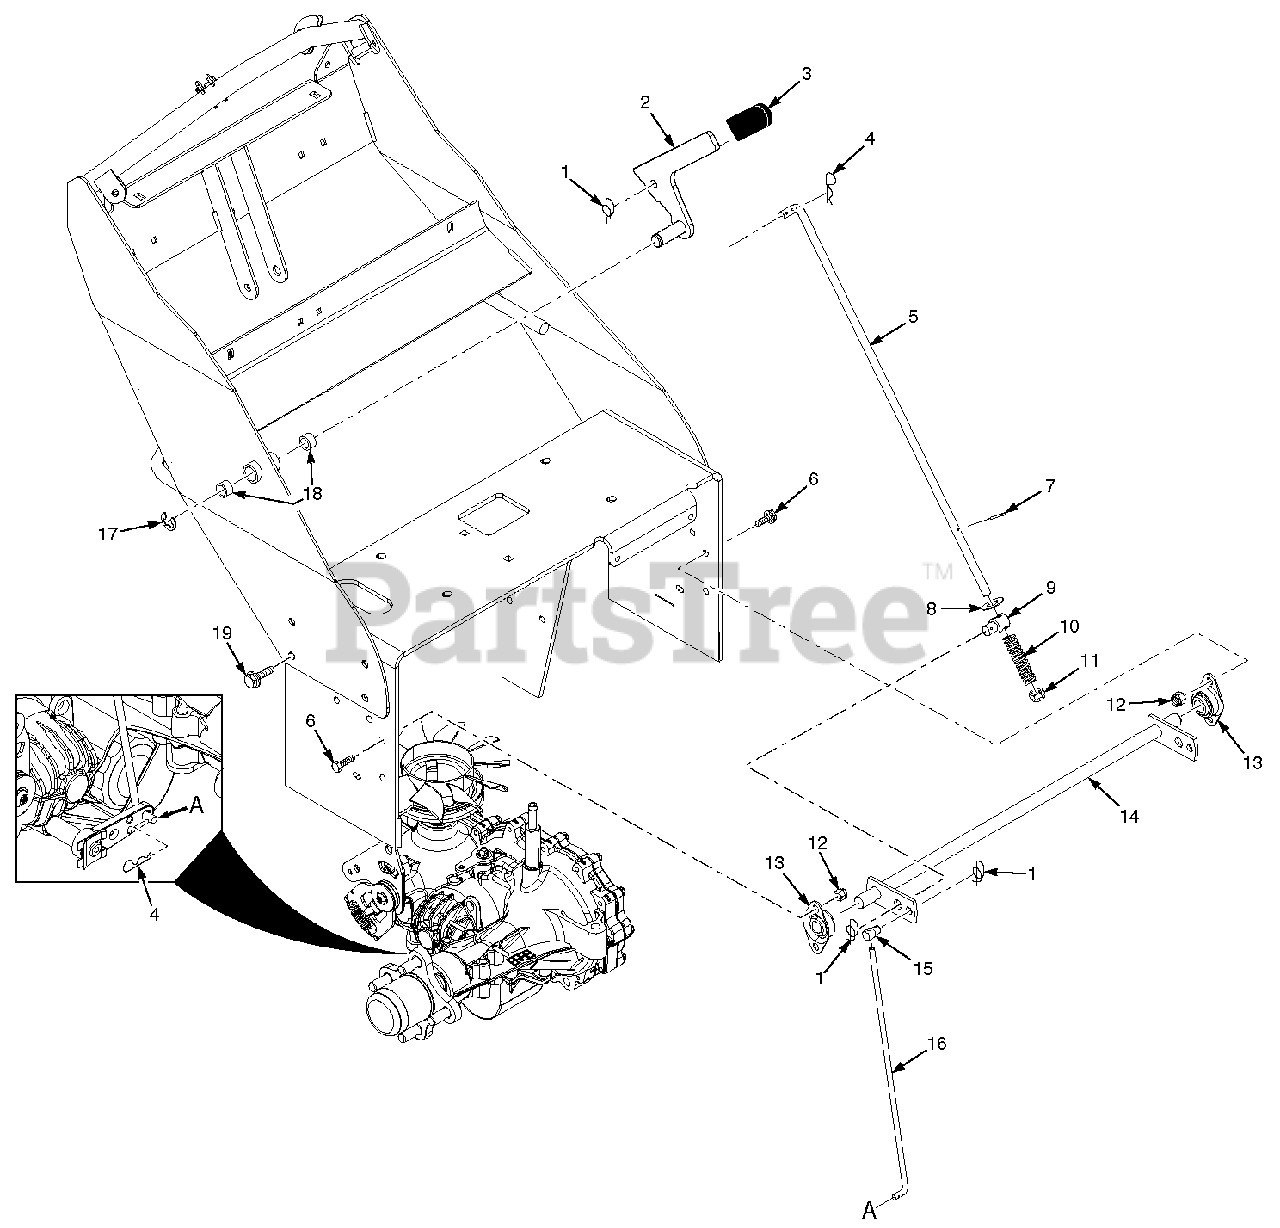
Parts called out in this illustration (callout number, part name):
1	Pin, Rue Cotter 3/8" Dia.
2	Brake Lever w/Grip
3	Grip, Brake Lever
4	Hair Pin, .080 x 1.19"
5	Rod, Brake Linkage
6	Cpscrw, 5/16-18 x 3/4"Serrated Flange HH
7	Cotter Pin, 3/32 x 3/4"
8	Flatwasher, 3/8-.406 x .812 x .065
9	Bushing, Pivot Slide
10	Spring, Brake
11	Nut, Elastic Stop 3/8-24
12	Nut, Elastic Stop 5/16-18
13	Bearing, Self Aligning 5/8" I.D.
14	Weldment, Brake Bellcrank
15	Joint, Swivel
16	Rod, Brake Adjustment
17	Ring, Retaining 5/8" External "E"
18	Bearing
19	Cpscrw, 3/8-16 x 1"Serrated Flange HH
